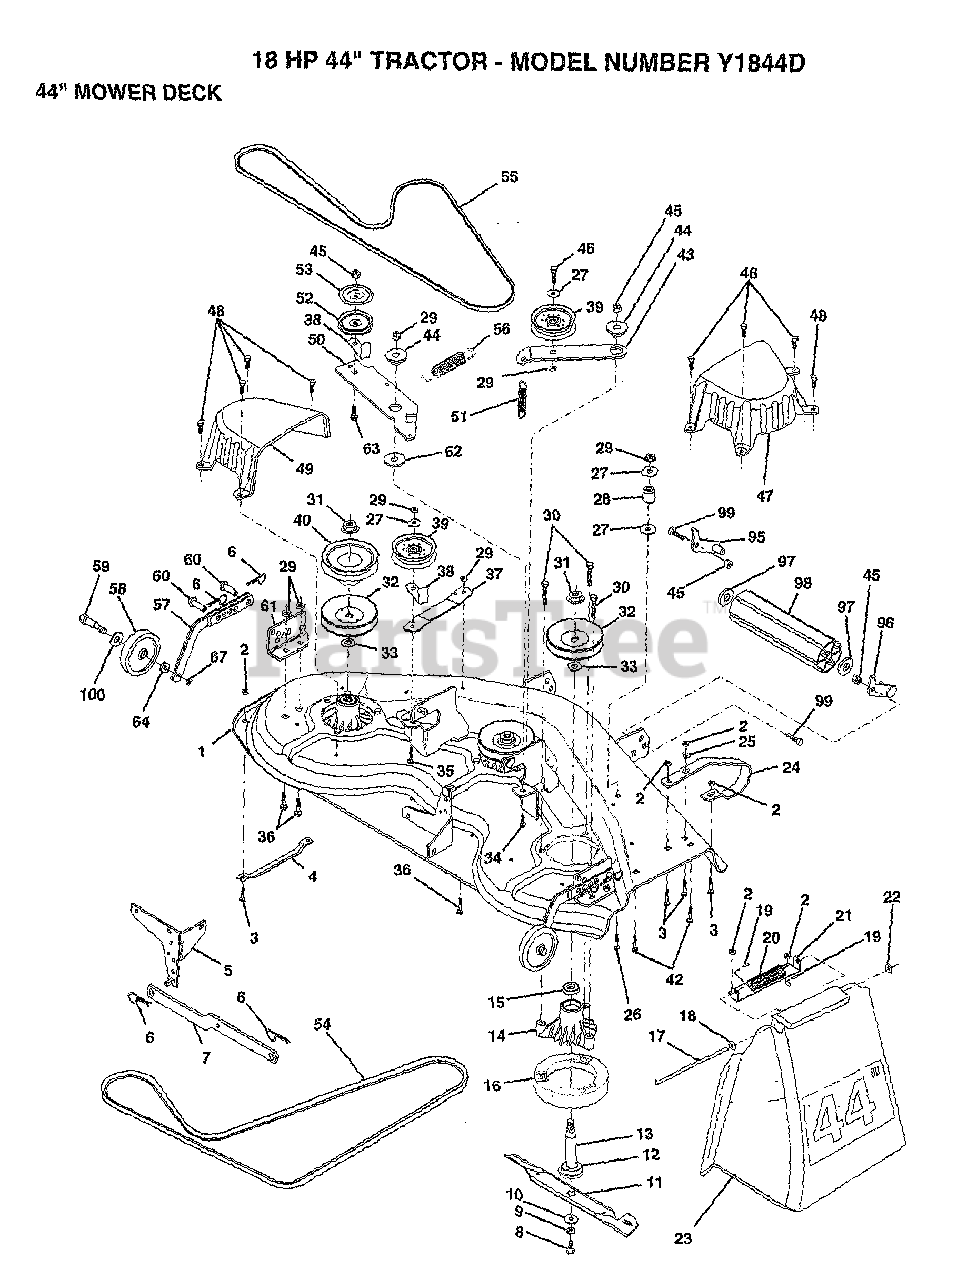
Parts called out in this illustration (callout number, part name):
1	"DECK ASM WELD44"""
2	NUT
4	RUNNER-LH M
5	BRKT.ASM.SW.44/50
8	BLADE BOLT
10	WASHER.HARD.BLADE
11	"BLADE.44"" HIPERF"
12	BEARING.BALL
13	SHAFT.ASM.W/BRNG
14	HOUSING.MAND.44.V
15	BEARING
17	ROD-HINGE T
18	WASHER
19	CAP-SLEEVE LT
20	SPRING TORSION
21	BRKT DEFLECTOR
22	NUT PUSH M
23	DEFLECTOR SHIELD
24	RUNNER.RH
25	WASHER M
26	BOLT
27	WASHER
29	NUT
33	WASHER
34	BOLT.3/8-14X1.25
35	BOLT
36	BOLT D
37	STIFFENER.ARM.IDL
39	FLAT IDLER PULLEY
40	"PULLEY.DRIVEN.44"""
42	BOLT
43	"ARM.IDLER.SEC.44"""
44	SPACER RETAINER
47	"COVER.MAND.RH.44"""
48	SCREW.1/4-20X5/8
49	COVER.MANDREL.LH
50	ARM.IDLER.PRIMARY
51	"SPRING.SEC.44""VEN"
52	PULLEY.IDLER.VGRO
53	SHIELD.IDLER.44.V
54	V-BELT.PRIM.78.5.
55	BELT-V.88.12.MW
56	SPRING.EXT.DECK.
57	BAR.ASM.GUAGE.WHL
58	WHEEL.GAGE.BLK.PL
59	BOLT M
60	PIN.CLEVIS
61	BRACKET.GUAGE.WHL
62	HARDENED WASHER
63	BOLT.3/8-16X1.50
64	WASHER
67	LOCKNUT
97	WASHER
99	BOLT
100	WASHER
